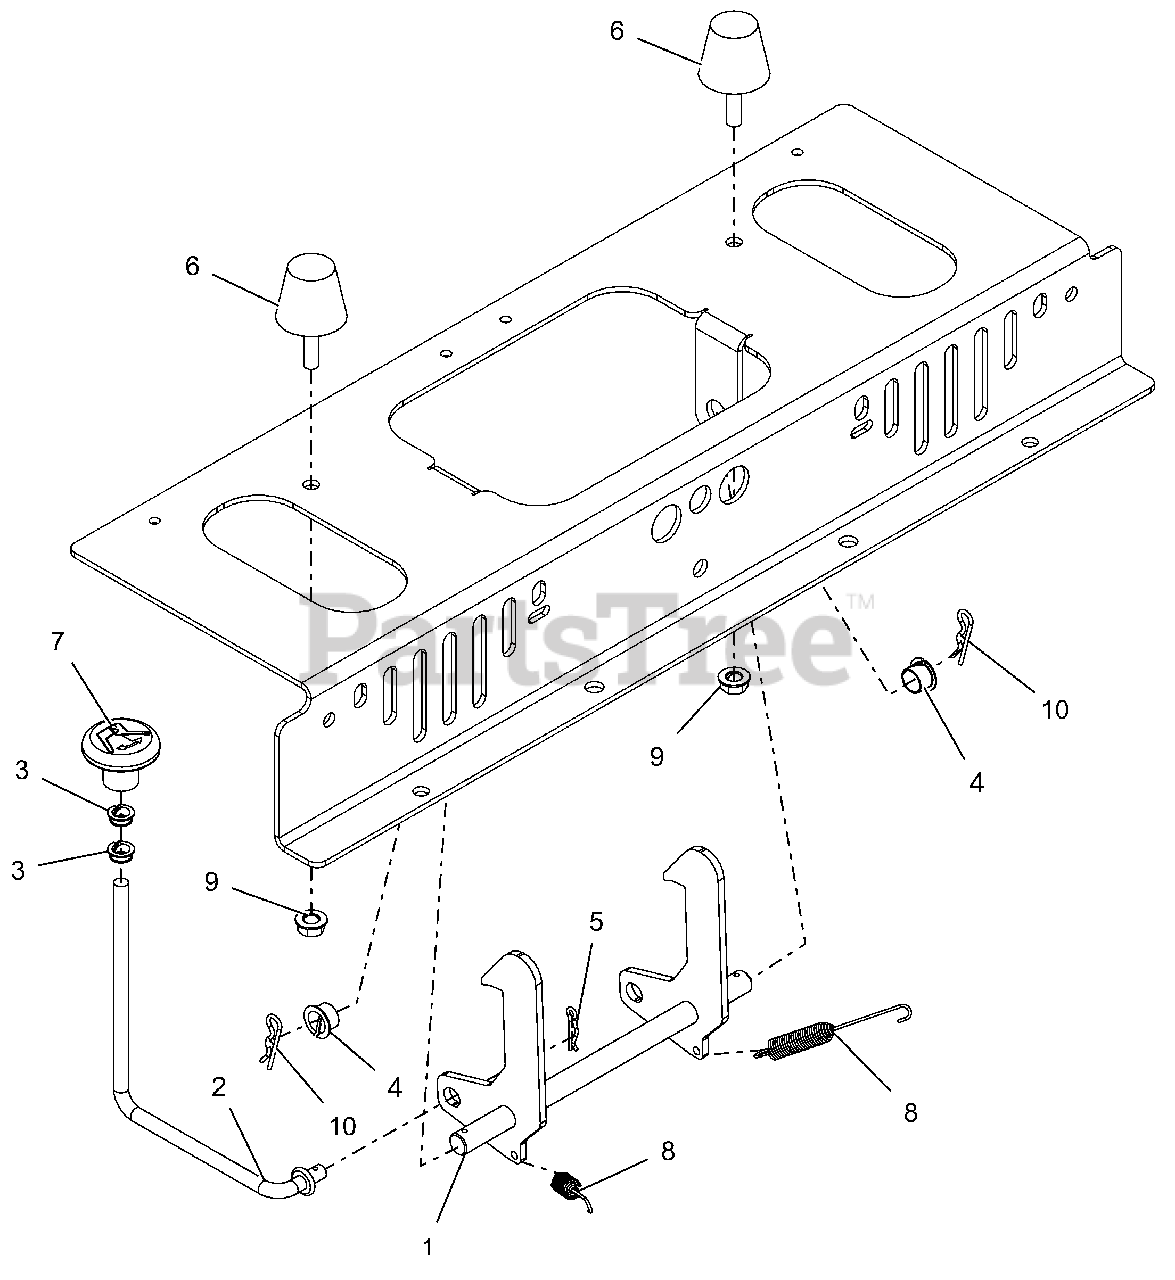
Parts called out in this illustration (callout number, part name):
1	SEAT LATCH WLDMT - LOW FILM
2	LINKAGE, SEAT RELEASE
3	BUSHING, POLYLINER-.38 SNAPIN
4	BUSHING, POLYLINER-.50 SPLIT
5	PIN-HAIR, ENDRIES #25 YWZC
6	BUMPER,STUD MOUNTED CONE SHAPE
7	KNOB, PUSH/PULL
8	SG-TENS .043X.44X3.31 WLD 5.8
9	@NUT-SPNLK-FLG .312-18 YWZC
10	PIN-HAIR INT .08X.38X1.42 YWZC
